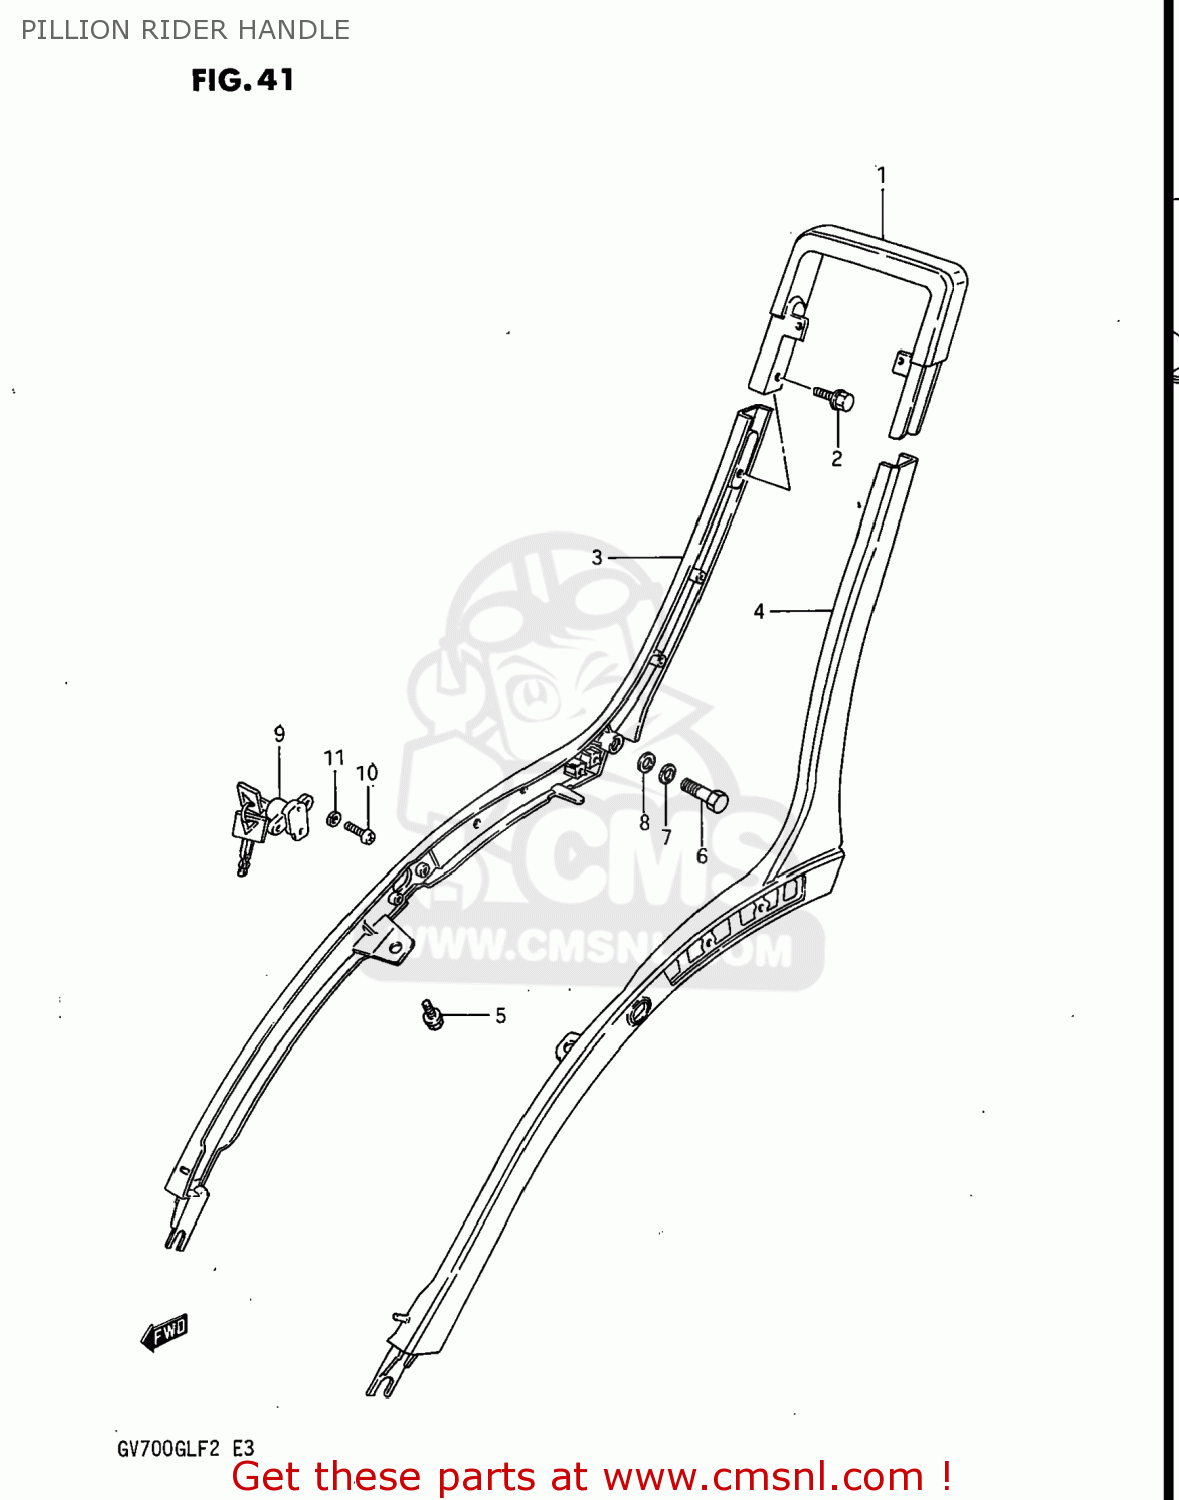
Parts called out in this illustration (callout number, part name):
1	HANDLE,PILLION RIDER U
2	BOLT
3	HANDLE,PILLION RIDER,RIGHT
4	HANDLE,PILLION RIDER,LEFT
5	BOLT 8X12
6	BOLT 10X30
7	LOCK WASHER
8	WASHER
9	LOCK ASSEMBLY,HELMET
10	SCREW
11	WASHER,LOCK
